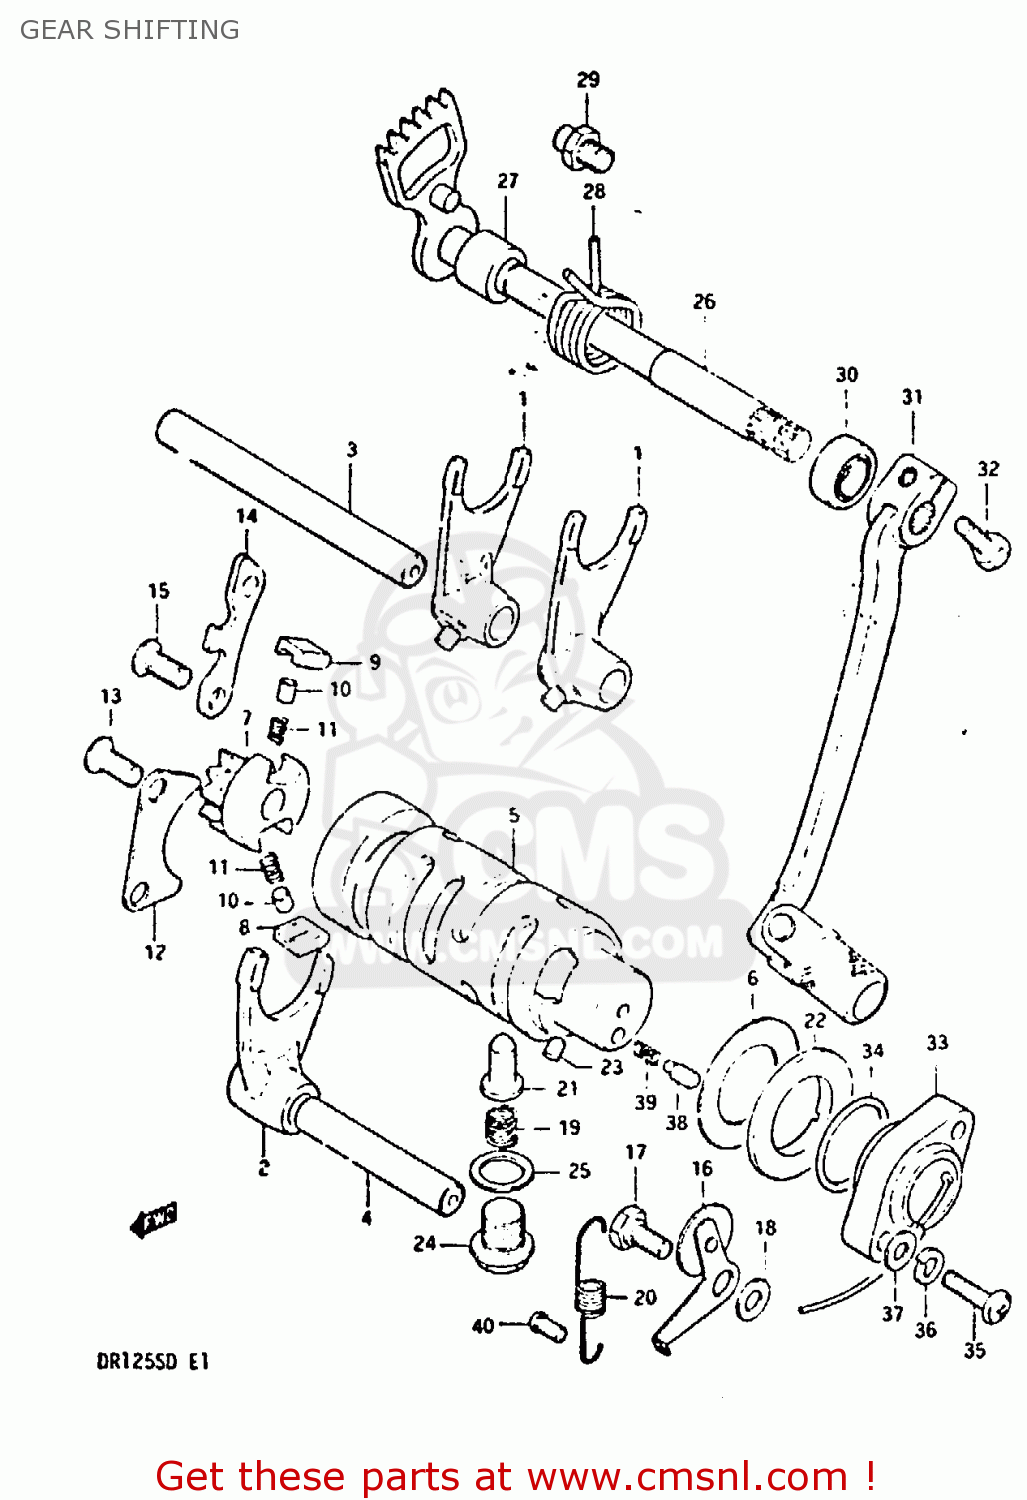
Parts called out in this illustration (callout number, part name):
1	FORK,GEAR SHIFT NO.1
2	FORK,GEAR SHIFT NO.3
3	SHAFT,GEAR SHIFT FORK
4	SHAFT,GEAR SHIFT FORK
5	CAM,GEAR SHIFT
6	WASHER,THRUST
7	RETAINER,GEAR SHIFT CAM
8	PAWL,GEAR SHIFT NO.1
9	PAWL,GEAR SHIFT NO.2
10	PIN(5X8)
11	SPRING
13	SCREW
14	GUIDE,GEAR SHIFT CAM
15	SCREW
16	STOPPER,GEAR SHIFTING
17	BOLT
18	WASHER
19	SPRING
20	SPRING
21	STOPPER,GEAR SHIFT CAM NO.2
22	PLATE,GEAR SHIFT CAM STOPPER
23	PIN 4X6
24	PLUG (14X12)
25	GASKET(14X19.2X2) (NAS)
26	SHAFT,GEAR SHIFT
27	SPACER(12X20X15.3)
28	SPRING
29	STOPPER,GEAR SHIFT CAM
30	OIL SEAL
31	LEVER ASSEMBLY,GEAR SHIFTING
32	BOLT
33	TERMINAL BASE,NEUTRAL SWITCH
34	O-RING (D:2.4 ID:26.2)
35	SCREW 5X20
36	LOCK WASHER
37	WASHER
38	PIN(5X15.5)
39	SPRING
40	RIVET
